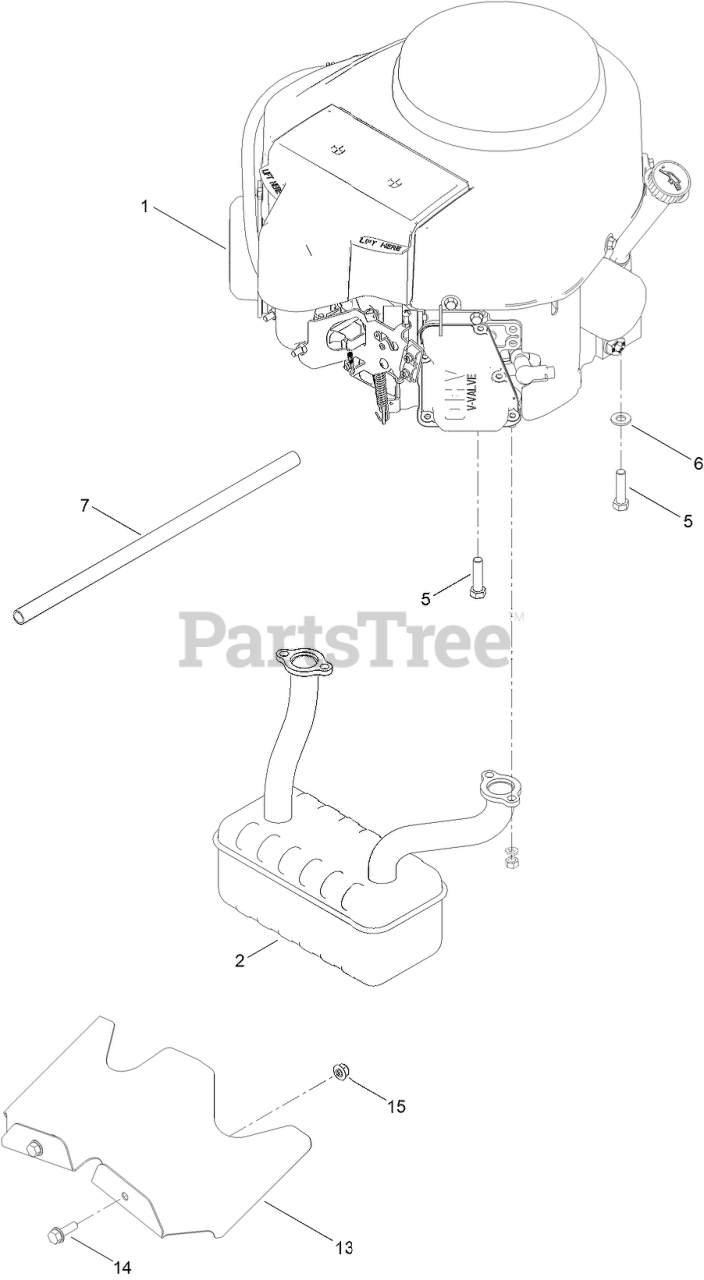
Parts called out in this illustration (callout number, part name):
2	MUFFLER
5	BOLT-HH
6	WASHER-FLAT
7	TUBE-DRAIN, OIL
13	SHIELD-HEAT
14	SCREW-HHF
15	NUT-HF, NI
